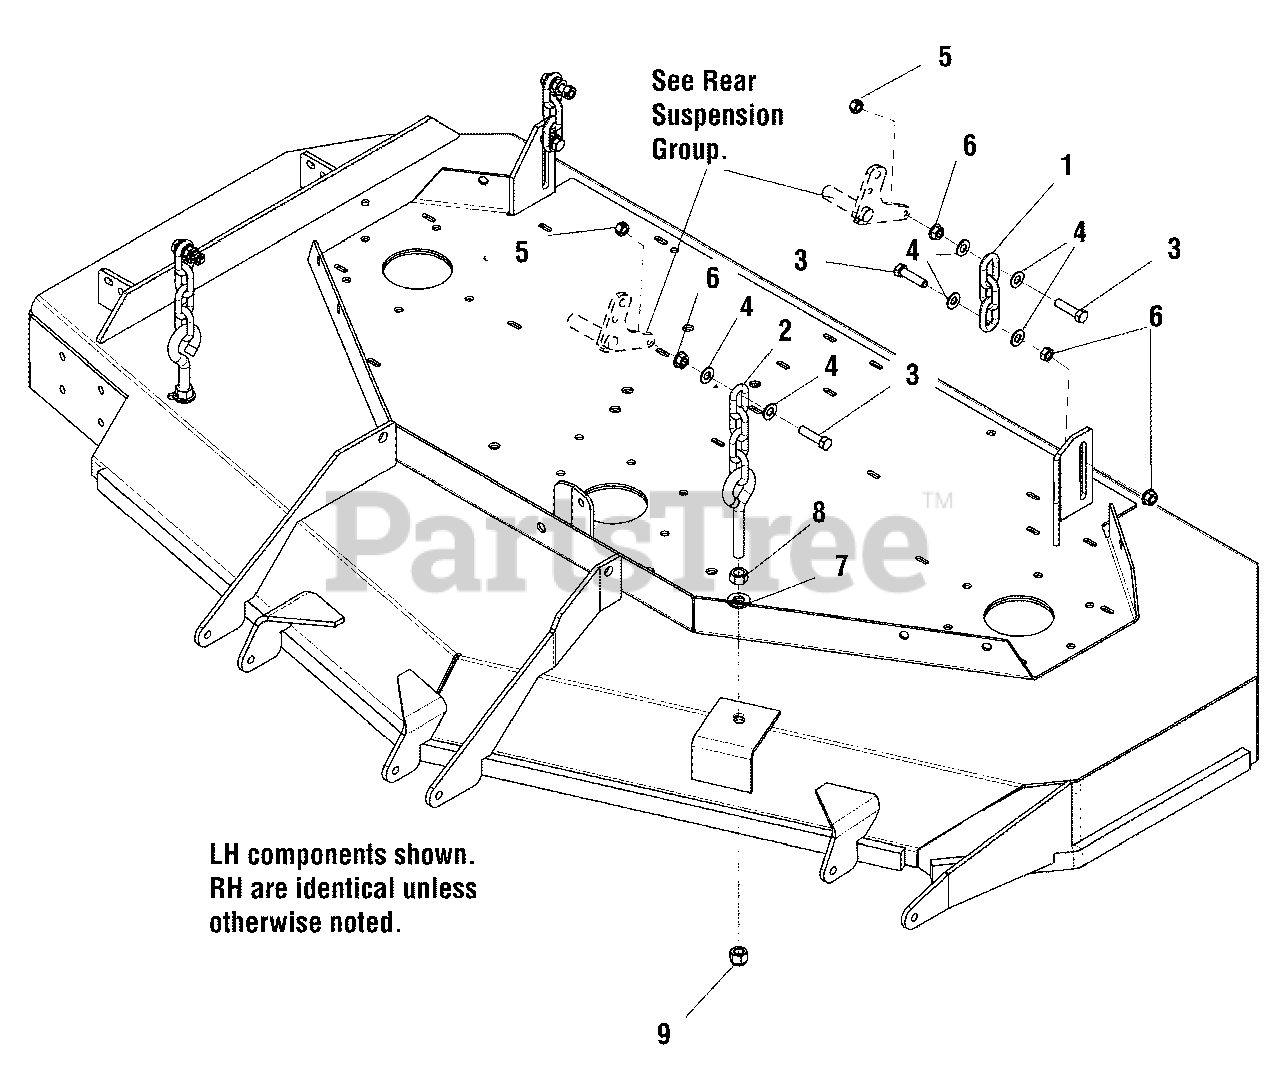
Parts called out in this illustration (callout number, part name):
1	CHAIN, 5/16 GD30, 3 LINKS
2	HANGER, FRONT DECK - 4 LINK, 5.5" EB
3	BOLT, 3/8-16 X 1-3/4 GD5
4	WASHER, 3/8 SAE
5	NUT, 3/8-16 HEX SERRATED FLANGE
6	NUT, 3/8-16 HEX SIDE LOCK
7	WASHER, 1/2 SAE
8	NUT, 1/2-13 HEX
9	NUT, 1/2-13 HEX NYLOCK FLANGE
